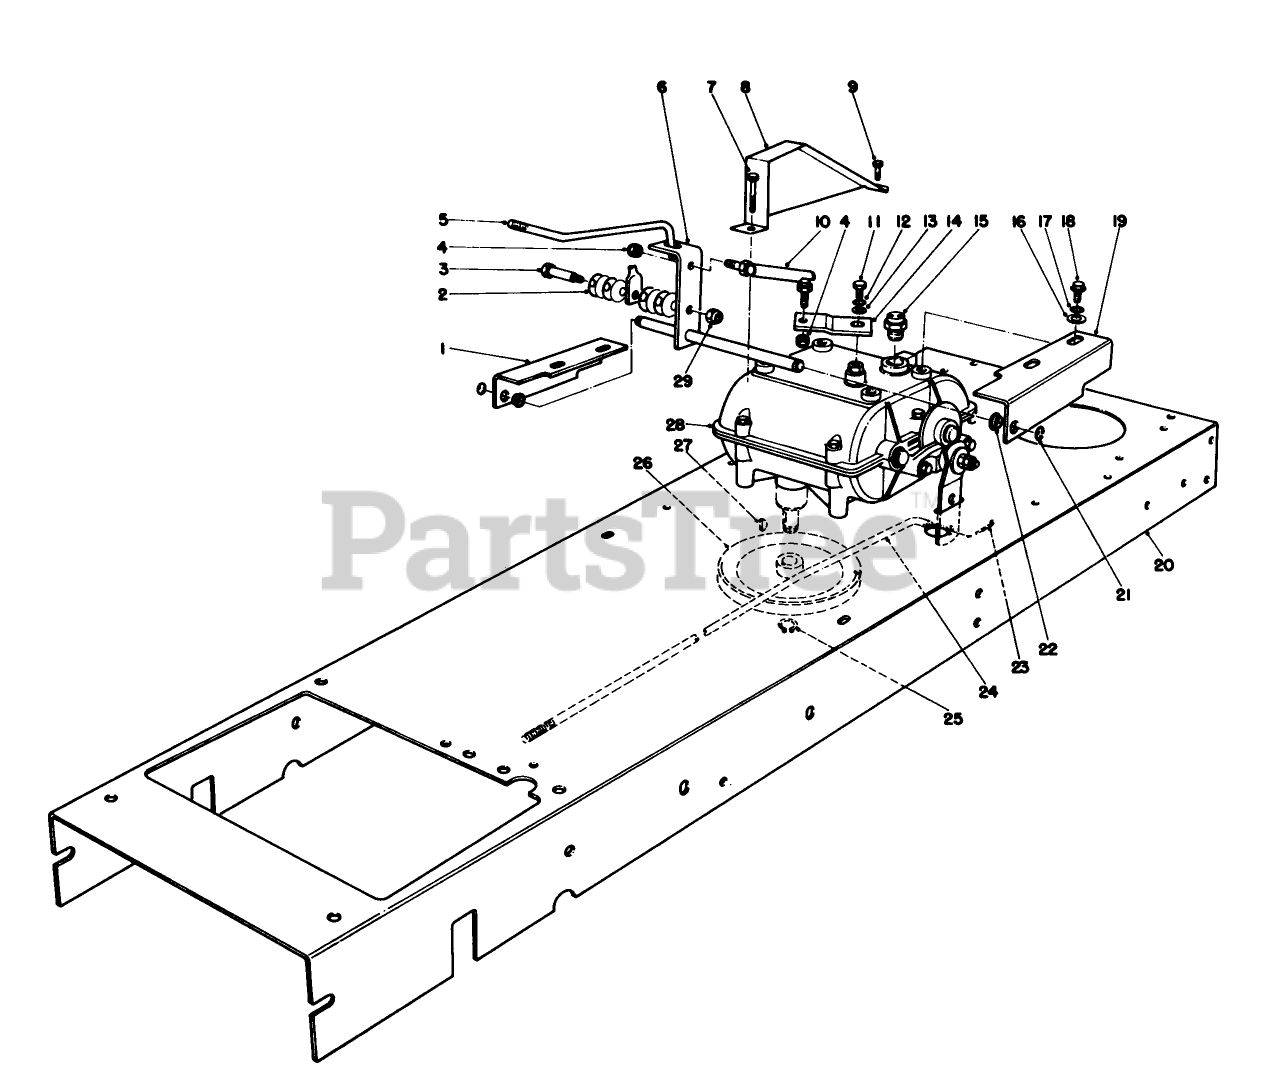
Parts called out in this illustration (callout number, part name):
2	WASHER-BELLEVILLE
3	BOLT-SHOULDER
4	NUT-LOCK, NI
5	WASHER-PLASTIC
6	SHIFT LEVER WA *B
7	SCREW-HH
9	SCREW-HH
10	Linkage-Tie Rod Shift
11	SCREW-HH
12	WASHER-LOCK
13	WASHER-FLAT
15	NEUTRAL SWITCH
16	WASHER-PLAIN
17	WASHER-LOCK
18	SCREW-THD ROLL, HWH
19	Bracket-Shift L.H.
23	PIN-COTTER
25	RING-SNAP, EXTERNAL
26	PULLEY
27	KEY-WOODRUFF
29	NUT-LOCK, NI
